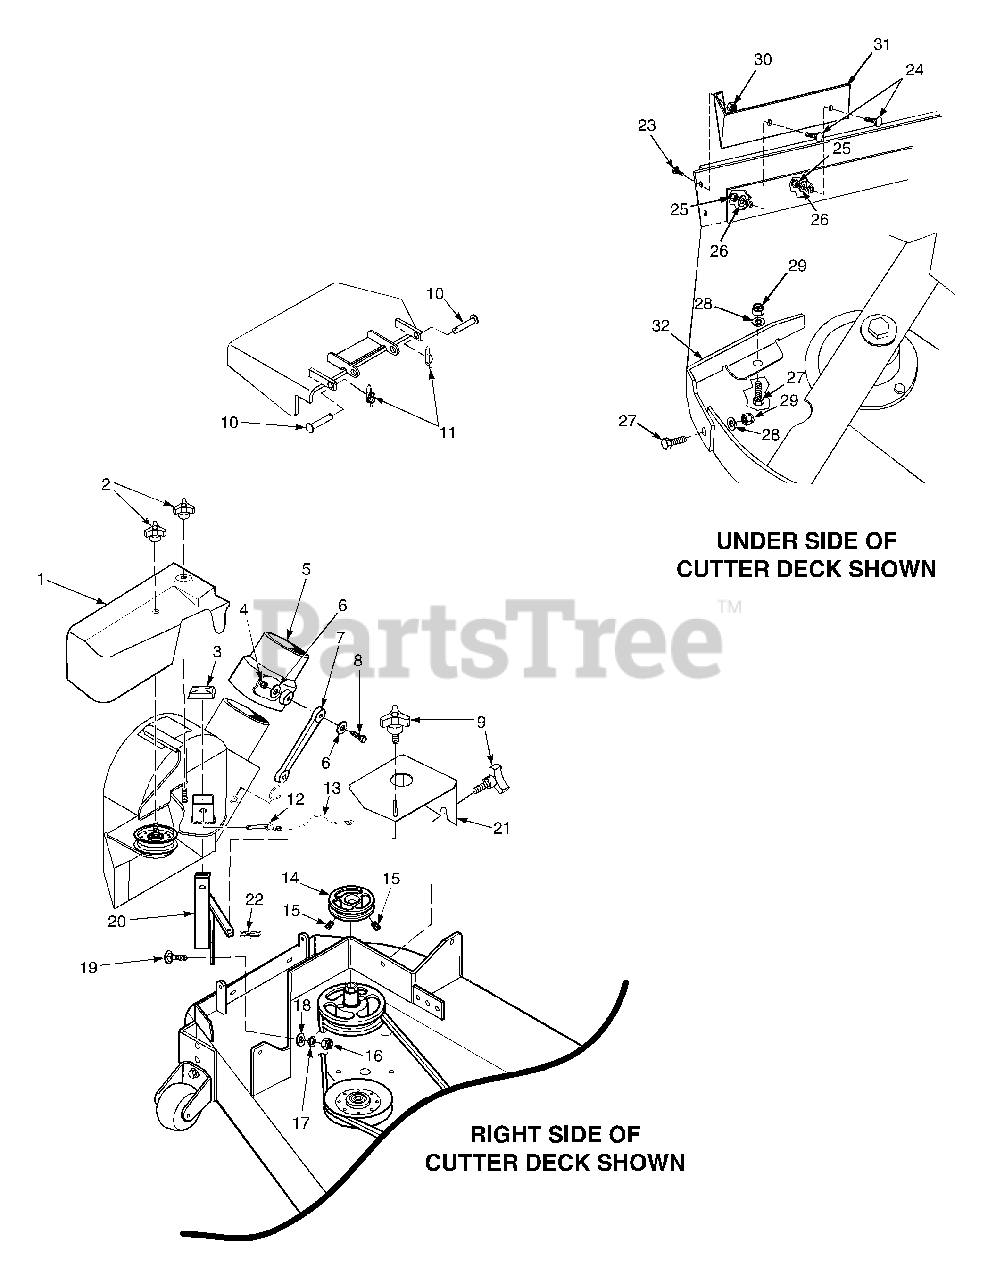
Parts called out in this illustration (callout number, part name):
1	Belt Cover, GC-STC
2	Wingnut, Plastic 3/8 Small
3	Cap, Square Vinyl
4	Nut, Elastic Stop 1/4-20
5	Adapter, Blower GC-STC,
6	Flatwasher, 1/4-.312 x .750 x .065
7	Rubber Strap 7-3/4"
8	Bolt, Hex Head 1/4-20 x 1-1/4"
9	Knob W/Stud, 3/8-16 x 1-1/4"
10	Clevis Pin, 5/16 x 1-1/2"
11	Pin, Rue Cotter 5/16 Dia.
12	Pin, Ring 1/2 x 2-1/4"
13	Lanyard
14	Pulley, 3-3/4" for 48" Deck
15	Setscrew, 5/16-18 x 3/8"
16	Nut, Elastic Stop 3/8-16
17	Lockwasher, 3/8"
18	Flatwasher, 3/8-.391 x .938 x .105
19	Bolt, Carr. 3/8-16 x 1-1/4" Grade 5
20	Mounting Post Weldment, Blower
21	Belt Cover
23	Bolt, Hex Head 1/4-20 x 3/4"
24	Bolt, Carriage 3/8-16 x 1"
25	Nut, Elastic Stop 3/8-16
26	Flatwasher, 3/8-.391 x .938 x .105
27	Bolt, Hex Head 5/16-18 x 1"
28	Flatwasher, 5/16-.375 x .875 x .083
29	Nut, Elastic Stop 5/16-18
30	Nut, Serrated Flange 1/4-20
31	Baffle, 48"
32	Baffle, 48" Deck
